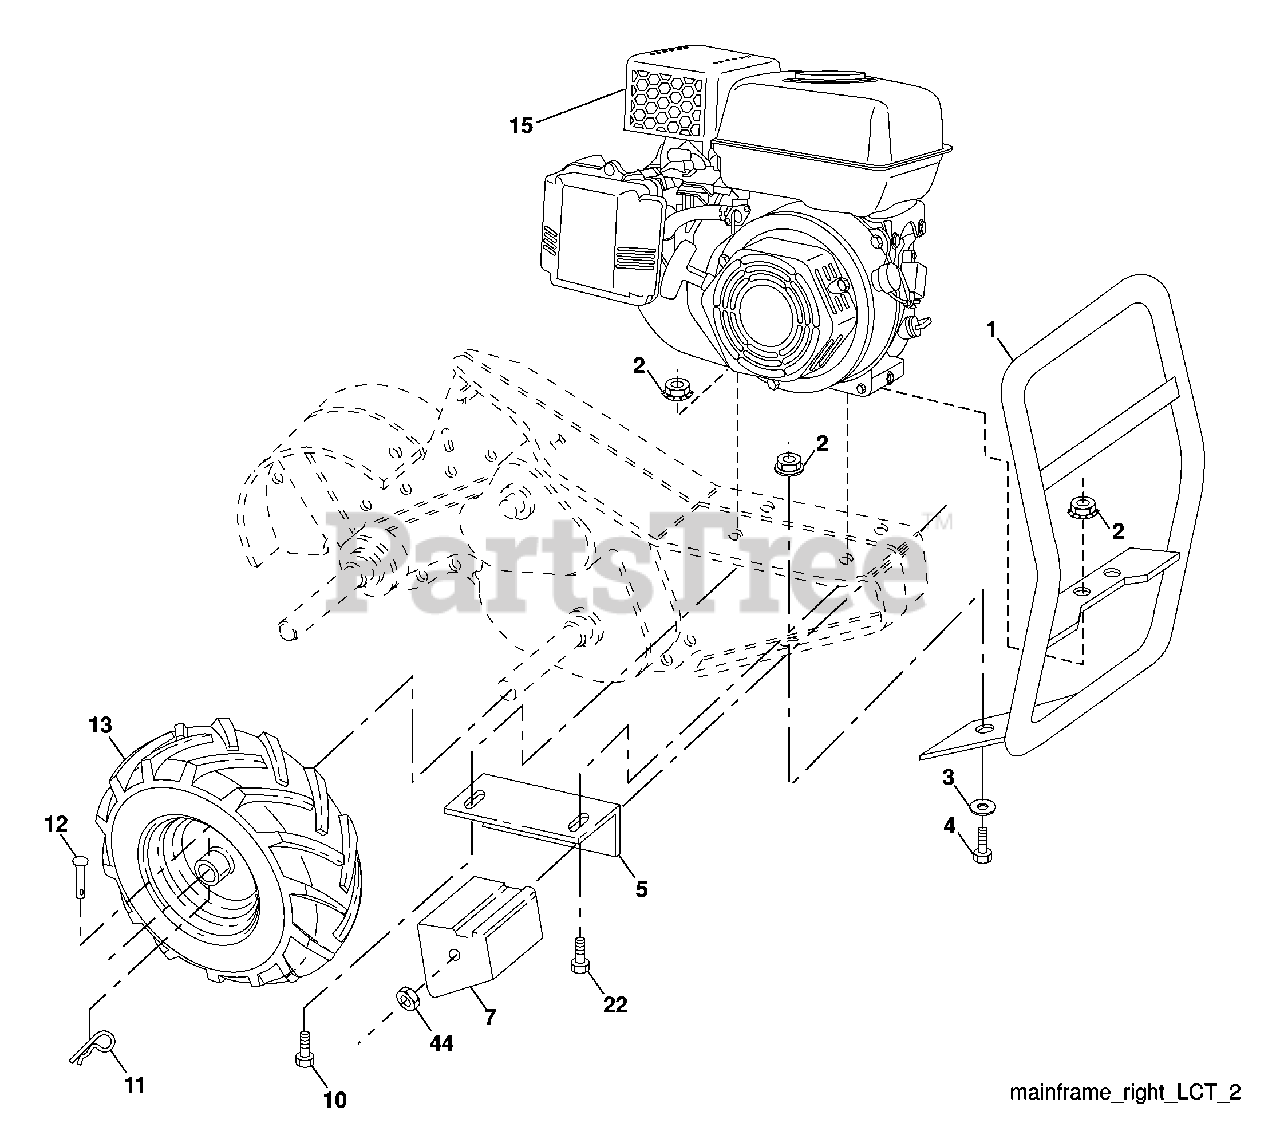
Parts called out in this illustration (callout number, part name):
1	Bumper Asm.
2	Locknut, Hex, Flange 5/16-18
3	Washer 11/32 x 11/16 x 16 Ga.
4	Bolt 5/16-18 x 3/4
5	Bracket, Reinforcement R.H.
7	Counter Weight, R.H.
10	Bolt, Hex 5/16-18 x 1-1/2
11	Clip, Hairpin
12	Rivet, Drilled
22	Bolt 5/16-18 x 1-3/4
44	Nut Keps Hex 3/8-16 unc
